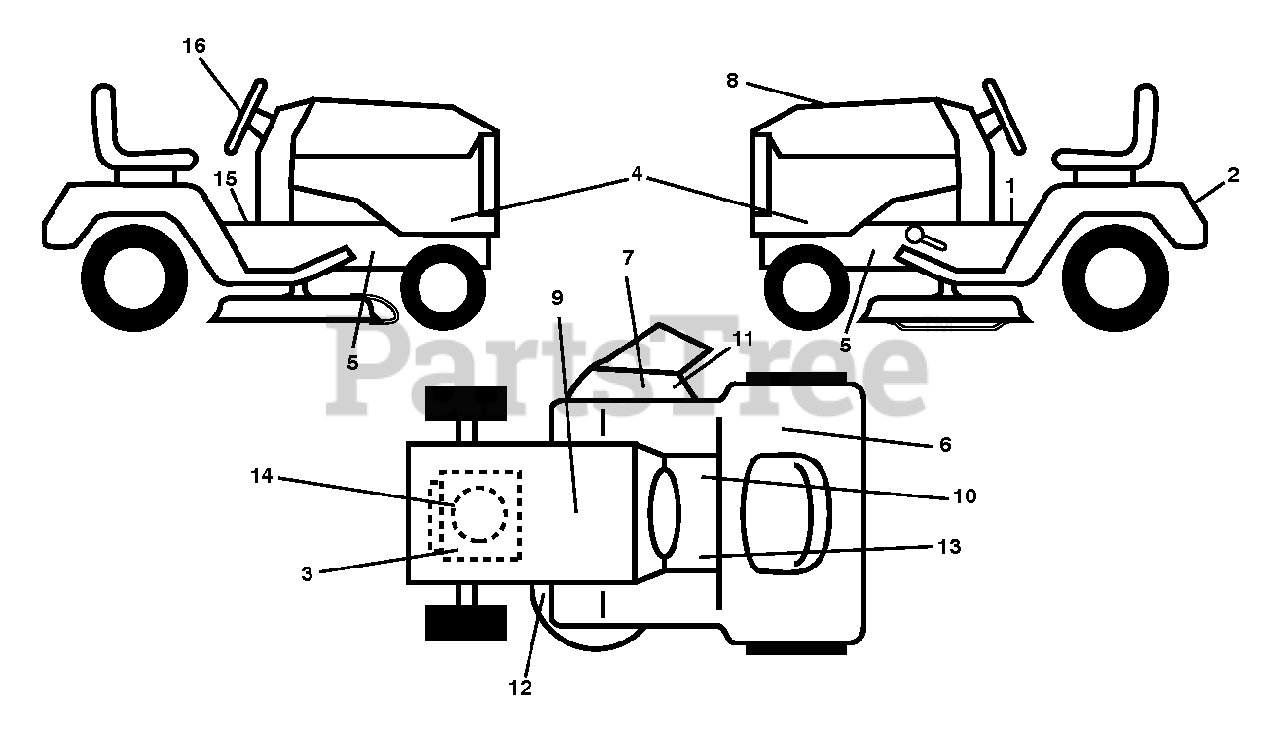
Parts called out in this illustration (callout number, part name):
7	DECAL.INTERNATIONL.CUTFINGER
9	DECAL BTRY SYMBOLS
10	DECAL PARK BRAKE
11	DECAL, DEFLECT WARNING
12	DECAL V BELT SCHEMATIC
